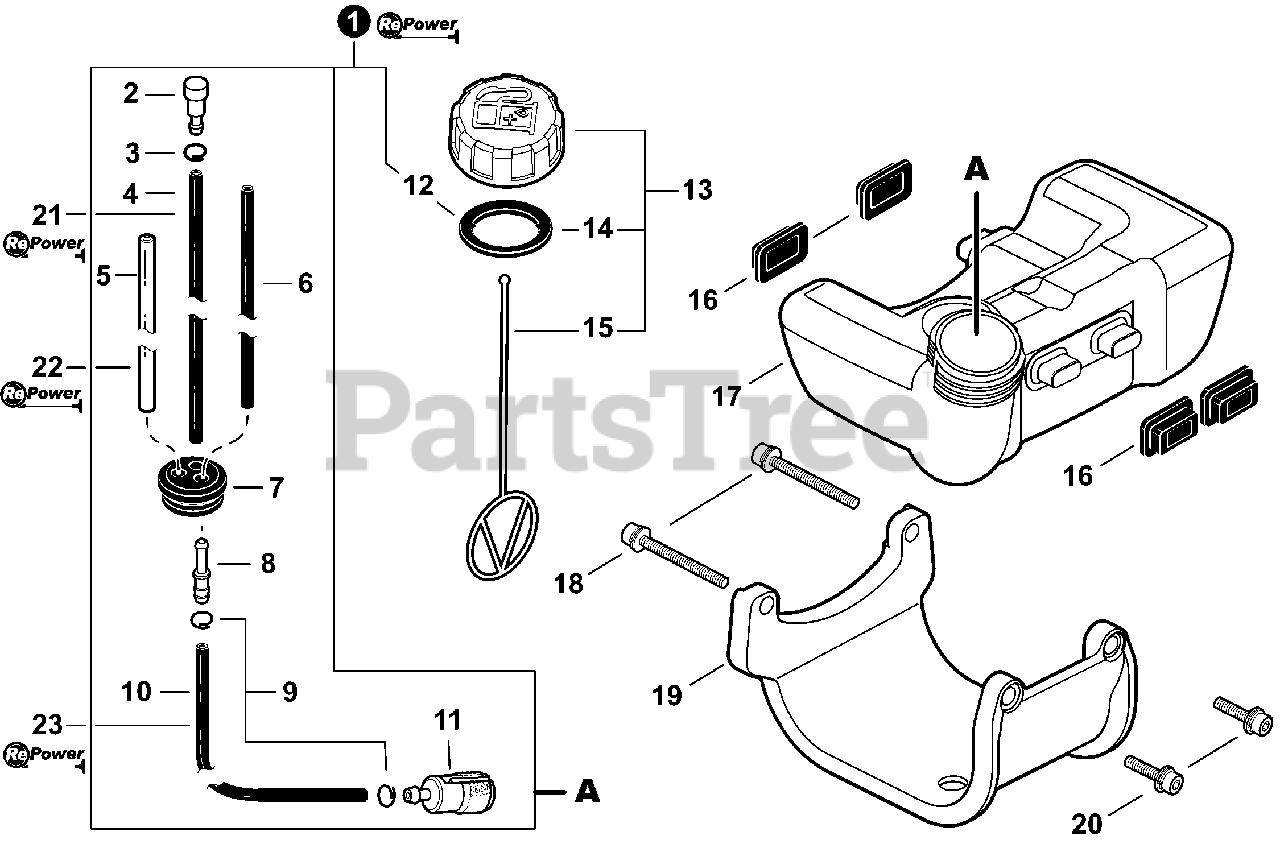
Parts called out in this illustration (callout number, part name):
1	FUEL SYSTEM KIT - REPOWER
2	VENT ASSY
3	CLIP 6.5MM
4	PIPE, FUEL 3×6×105 BLACK
5	PIPE, FUEL 3×6×85 CLEAR
6	PIPE, FUEL 3×5×74 BLACK
7	GROMMET, FUEL
8	CONNECTOR, PIPE 5×3.5
10	PIPE, FUEL 3×5×140 BLACK
11	FILTER, FUEL
12	GASKET, FUEL CAP
13	CAP ASSY, FUEL
14	GASKET, FUEL CAP
15	CONNECTOR, CAP L= 123
16	CUSHION, FUEL TANK
17	TANK, FUEL
18	BOLT 5×40
19	GUARD, FUEL TANK
20	BOLT 5×18
21	PIPE, BULK - REPOWER 3×6mm BLACK
22	PIPE, BULK - REPOWER 3×6mm CLEAR
23	PIPE, BULK - REPOWER 3×5mm BLACK
